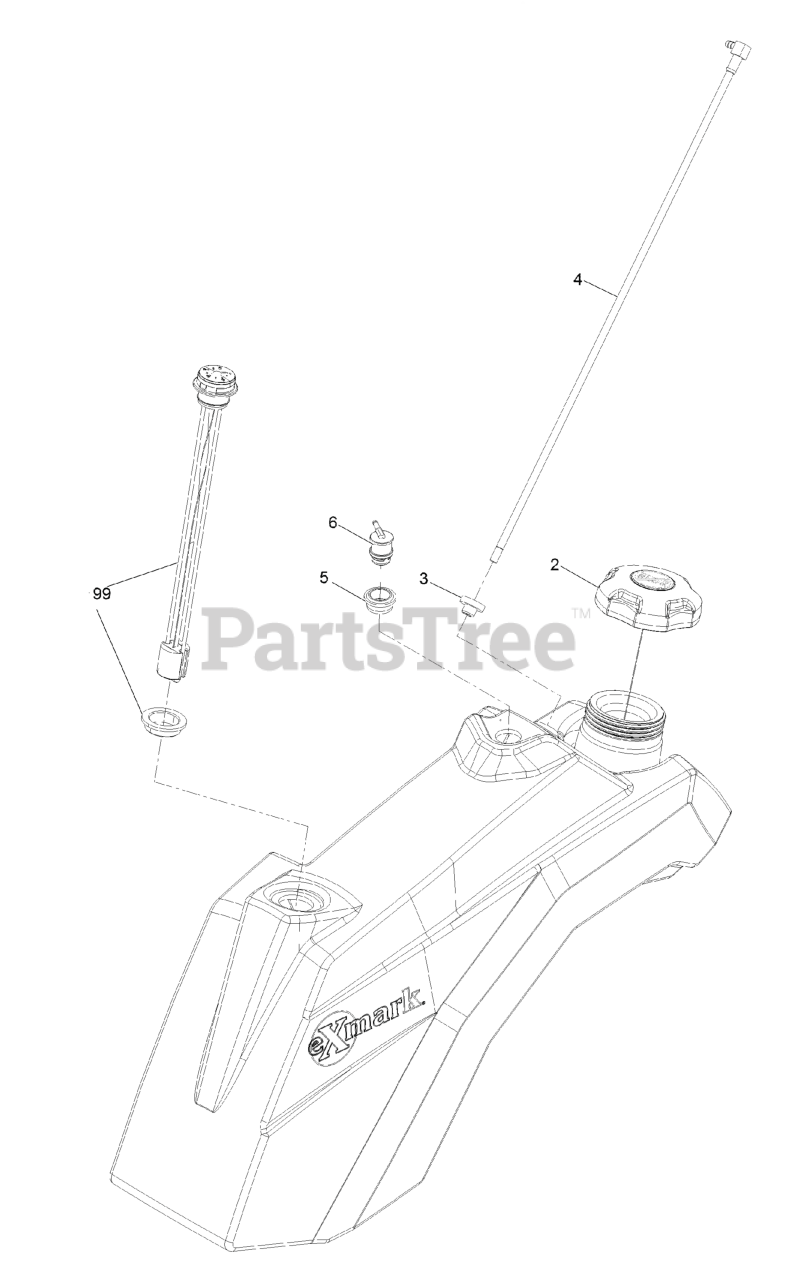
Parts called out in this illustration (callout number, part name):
2	CAP-FUEL, RATCHETING
3	BUSHING
4	STRAW, FUEL, LONG
5	GROMMET
6	VALVE-VENT, FUEL
99	KIT-FUEL GAUGE REPLACEMENT
